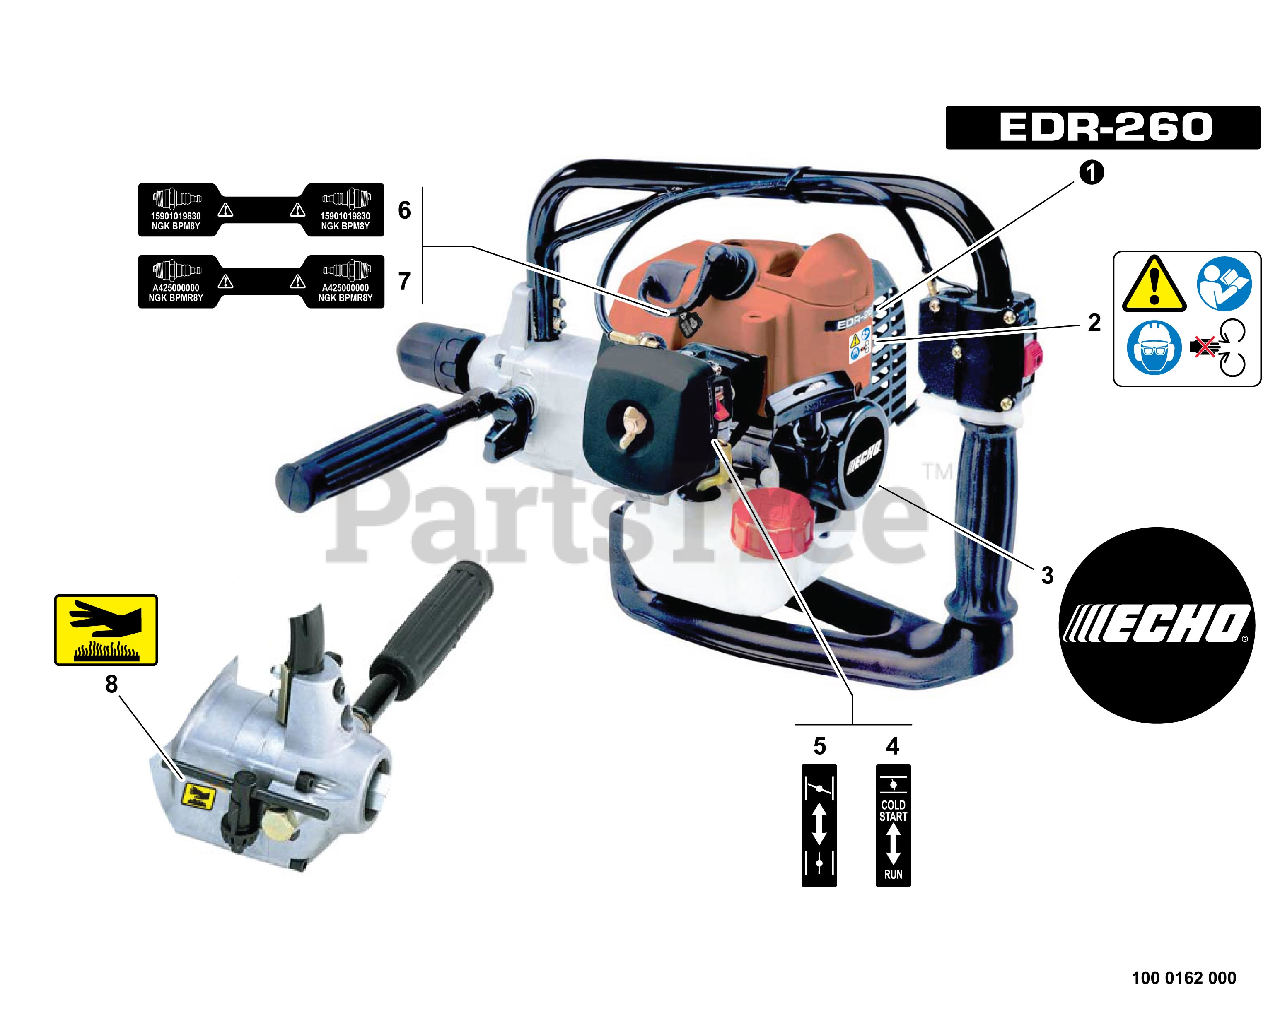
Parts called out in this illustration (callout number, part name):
1	LABEL - MODEL EDR-260
2	LABEL - HOT SURFACE
3	LABEL - ECHO
4	LABEL - CHOKE
5	LABEL - CHOKE
6	LABEL - SPARK PLUG -- BPM-8Y
7	LABEL - SPARK PLUG -- BPMR-8Y
8	LABEL - HOT SURFACE
